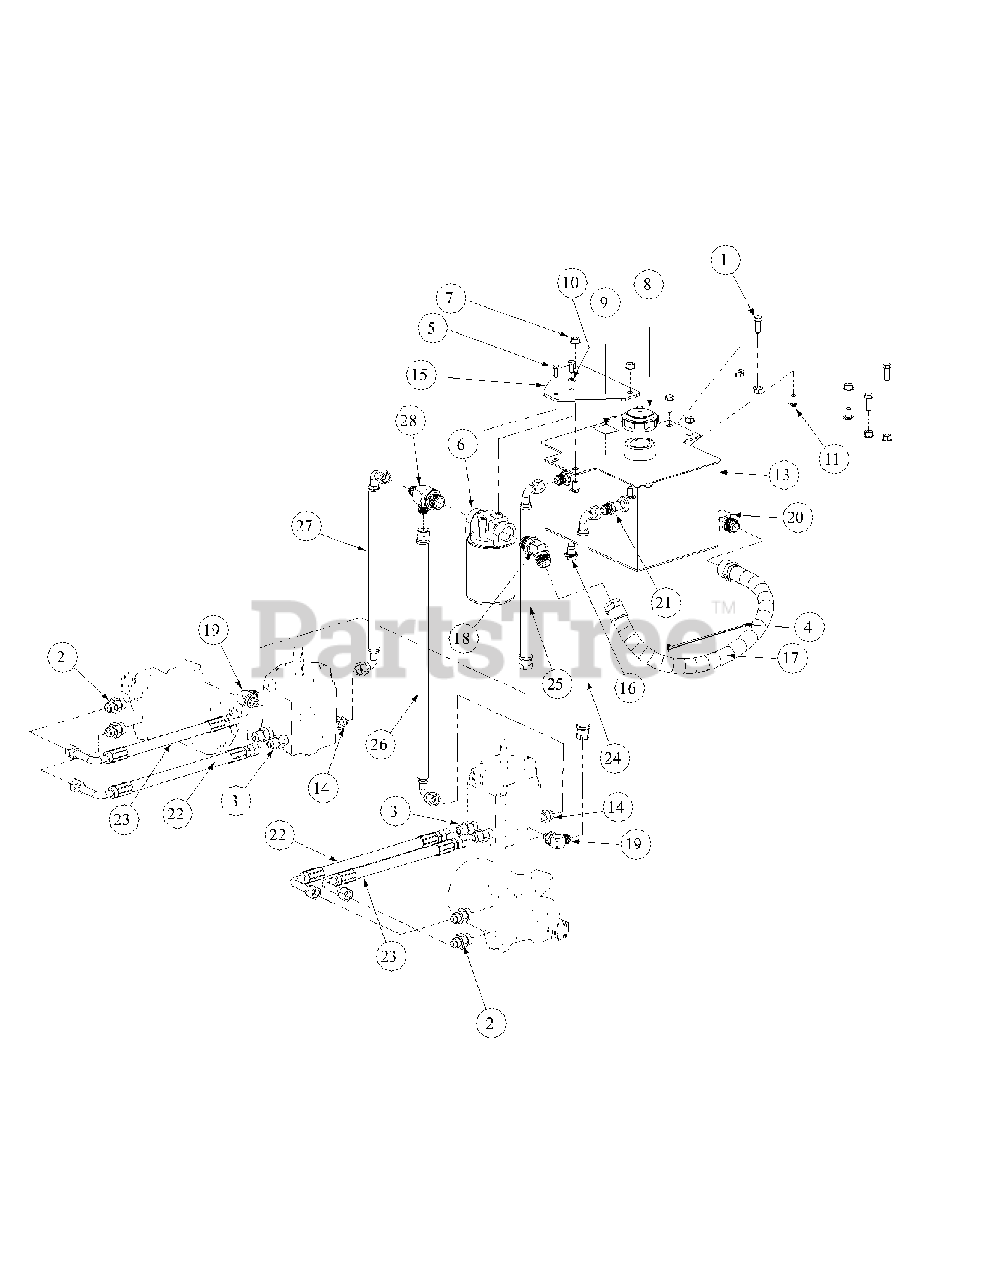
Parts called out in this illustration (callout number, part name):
1	Hex Cap Screw, 3/8-16, 1
2	Fitting 1/2 x 3/4 - O Ring
3	Fitting 1/2 x 3/4 - O Ring to Flare
4	Cable Tie, 3/16 x .05 x 7.4
5	Hex Cap Screw, 1/4-20, .75
6	Filter Head 3/4
7	Hex Nut Flange Lock, 3/8-16
8	Cap, Hydro Oil Tank
9	Decal Oil Only 20W50
10	Lock Washer, 1/4
11	Carriage Bolt, 3/8-16 x .75 LG.
13	Hydraulic Tank Assembly
14	Fitting Connector, 1/2 x 3/8
15	Oil Filter Mounting Plate
16	Oil Pan Drain w/ Seal and Plug
17	Tank to Filter Hose Assembly
18	Connector, 3/4 x3/4
19	Elbow Fitting, 3/8 O-ring, 1/2 Flare
20	Fitting Elbow, 1/2 x 1/2
21	Fitting, 3/8 NPT, 1/2 Flare
22	Long Pressure Hose Assembly
23	Short Pressure Hose Assembly
24	17.75" Return Hose Assembly, RH
25	14" Return Hose Assembly, LH
26	21.25" Supply Hose Assembly, RH
27	15.50" Supply Hose Assembly, LH
28	Tee Fitting, 3/4 x 1/2 x 1/2
